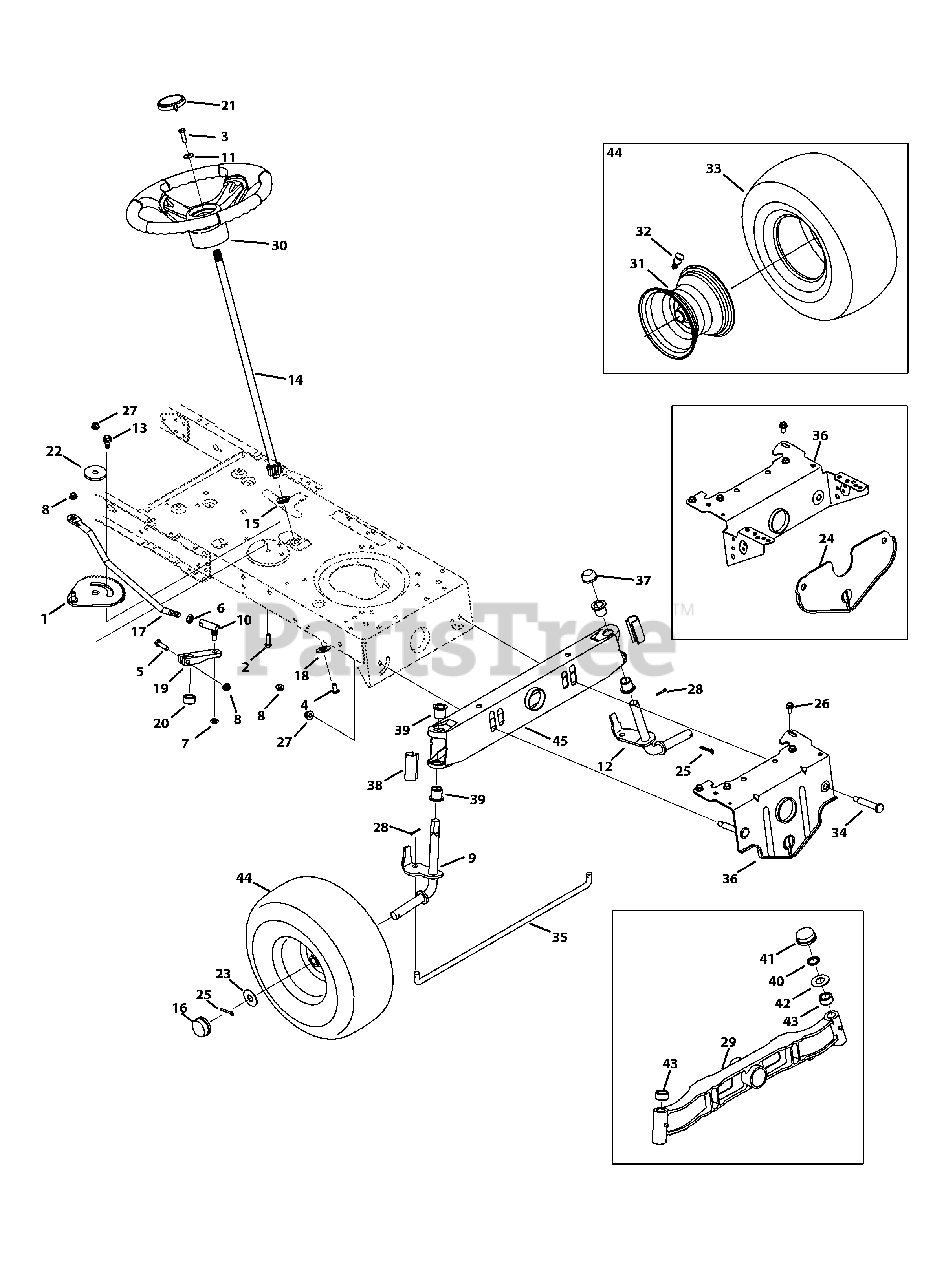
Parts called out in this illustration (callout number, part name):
1	Front Steering Gear Assembly
2	Hex Screw, 3/8-16 x 1.00
3	Hex Screw, 5/16-18 x 1.00, Lock
4	Machine Screw, 5/16-18 x .750
5	Hex Screw, 5/16-18 x 1.75
6	Jam Nut, 7/16-20
7	Jamlock Nut, 3/8-24
8	Flangelock Nut, 5/16-18
9	Front RH Axle
10	Ball Joint, 7/16-20
11	Bell Washer, .340 x .872 x .060
12	Front LH Axle
13	Shoulder Bolt, 5/16-18 x .435 x .350
14	Steering Shaft, 5/8 x 22.08
15	Flange Bearing, 5/8
16	Hub Cap
17	Steering Link
18	Cap, 1.25 x .16
19	Steering Block
20	Spacer, .71 x .125 x .56
21	Sprig Cap
22	Shoulder Spacer, .884 x .190
23	Flat Washer, .781 x 1.590
24	Front Deck Hanger Bracket
25	Cotter Pin, 5/32 x 1.25
26	Screw, 5/16-18 x .750
27	Flangelock Nut, 3/8-16
28	Cotter Pin, .125 x .75
29	Pivot Axle, Cast
30	Steering Wheel
31	Rim Asm, 6.0 x 4.5, 42"
32	Valve, tubeless Air
33	Tire, 15 X 6 X 6 Sq Shldr, 42"
34	Shoulder Bolt, 3/8-16 x .500 x 2.38
35	Fixed Rod
36	Pivot Bar Bracket
37	Push Cap, 3/4
38	Standard Axle Cap
39	Flange Bearing, .760 x .941 x 1.0
40	Push Nut, 3/4
41	Hub Cap
42	Flat Washer, .78 x 1.59 x .060
43	Spacer, .71 x .125 x .56
44	Wheel Assembly, 42" Sq. Tred
45	Pivot Axle, Steel
